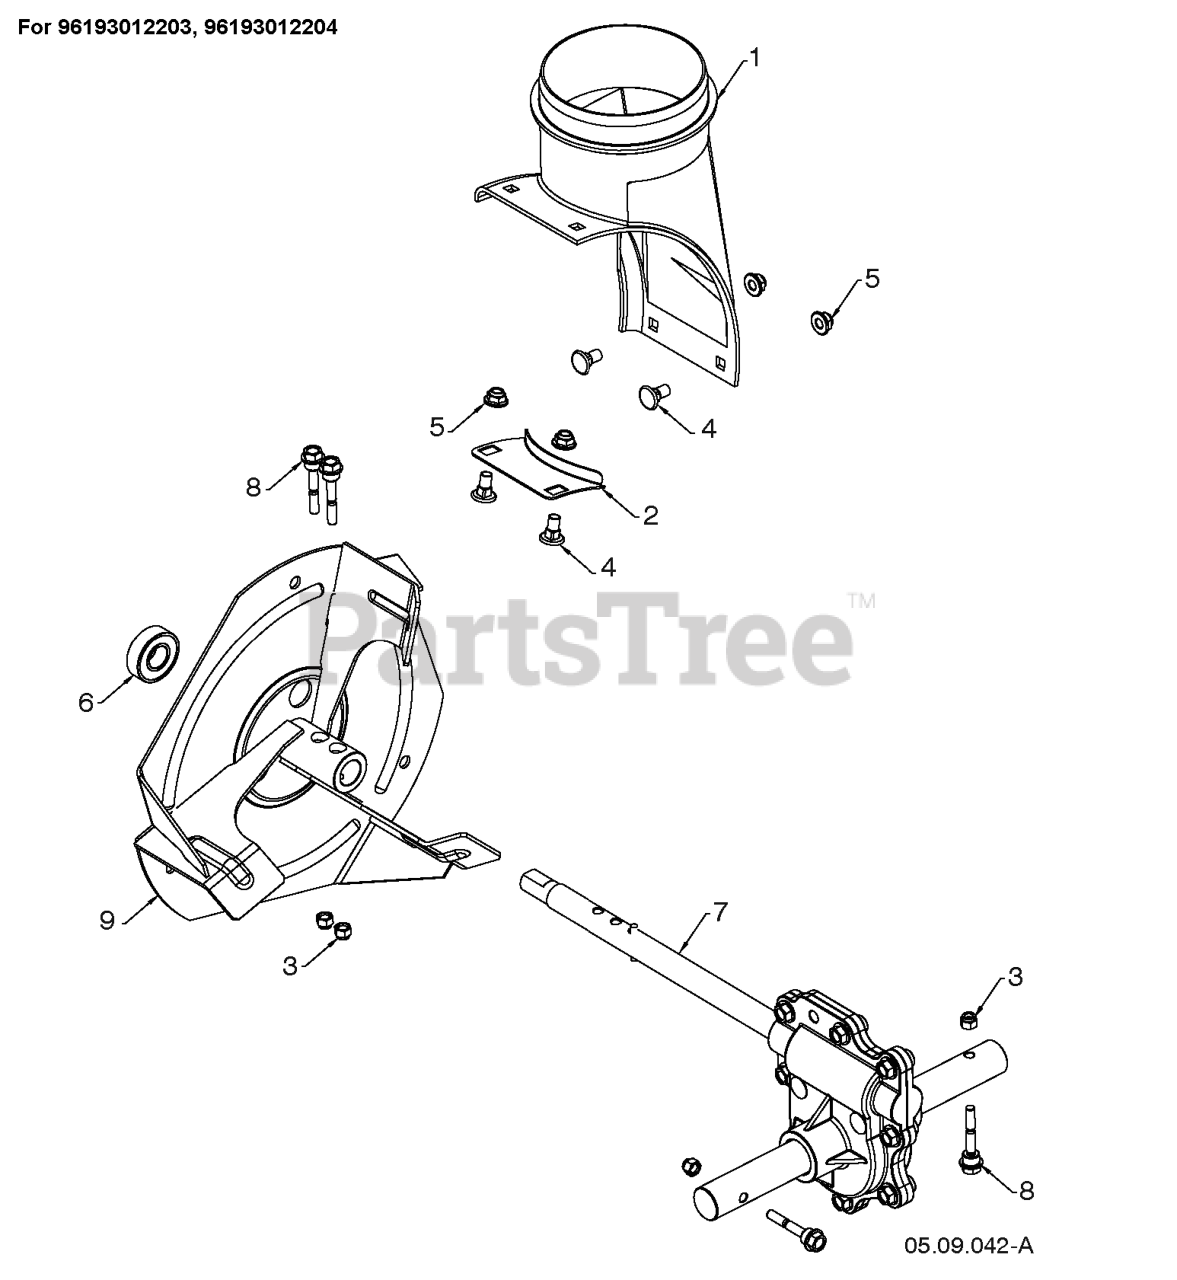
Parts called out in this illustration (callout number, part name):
1	CHUTE.DISCHARGE.BASE
3	NUT HEXAGON 1/4-20 ST ZPB
3	LOCKNUT.NYLOC.1/4-20
4	BOLT CARR WAFER BLK 5_16-18 X
5	NUT HEX FLG NYLOCK BLK 5_16-1
7	TRANSMISSION.GEARBOX.ALUM.DD
7	Gears
8	BOLT SHEAR HX HD 1/4-20 CLEAR
9	IMPELLER.STEEL.SNOW.BLACK
